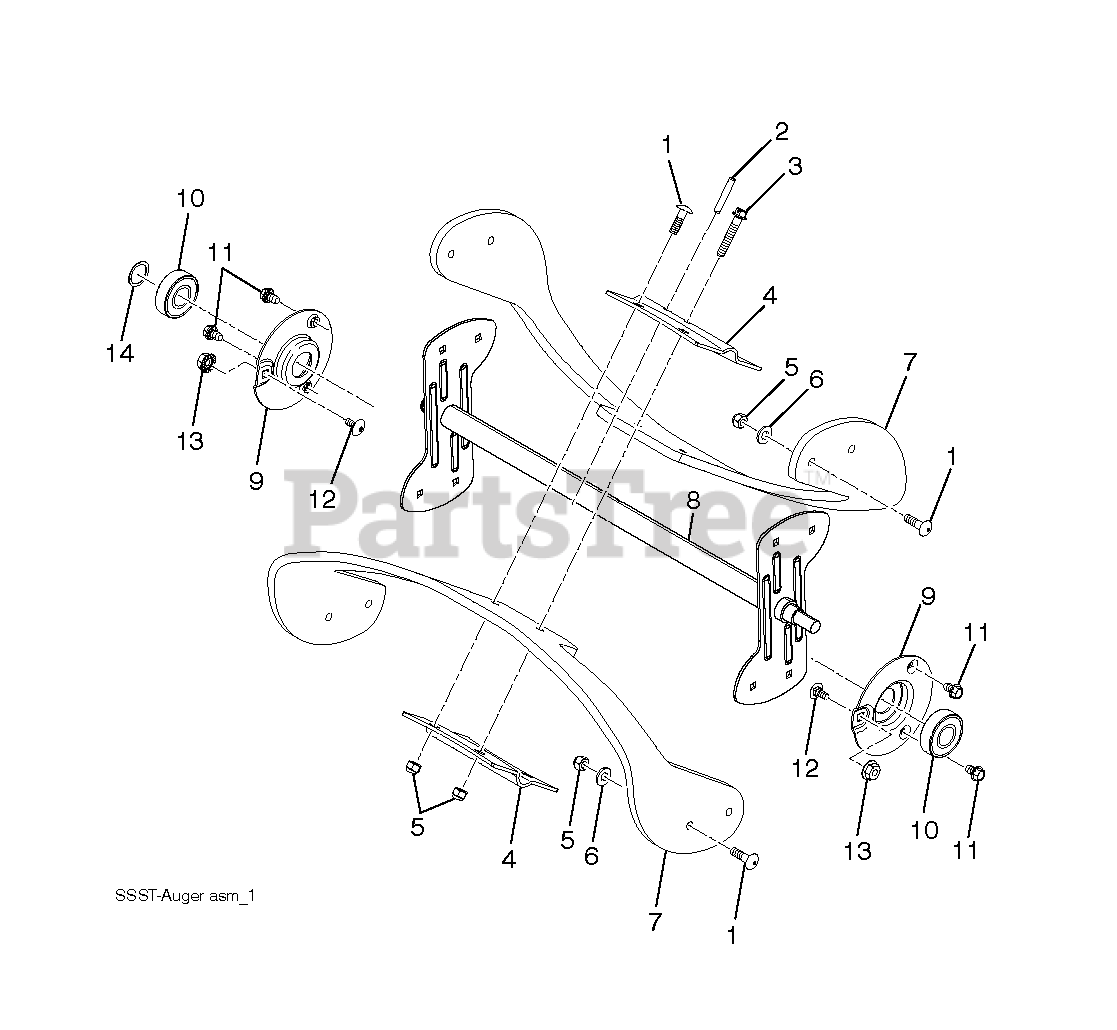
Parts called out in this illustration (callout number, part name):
1	PANEL.CONTROL.PNT.BLA
2	LEVER.CONTROL.LH.BLACK
3	LEVER.CONTROL.RH.GREY
4	ARM.TRACTION.ROD.YZ
5	ARM.IMPELLER.ROD.SNOW
6	BAIL.CONTROL.INTERLOCK
7	SPACER.CONTROL.LEVER
8	SPRING RETAINER
9	SCREW 14-20 X 5/8
10	KNOB BLACK
11	KNOBRED
12	KNOB.HANDLE.3/8.TRI-POINT.BLAC
13	WASHER
14	BOLT 3/8-16 X 2-1/4
